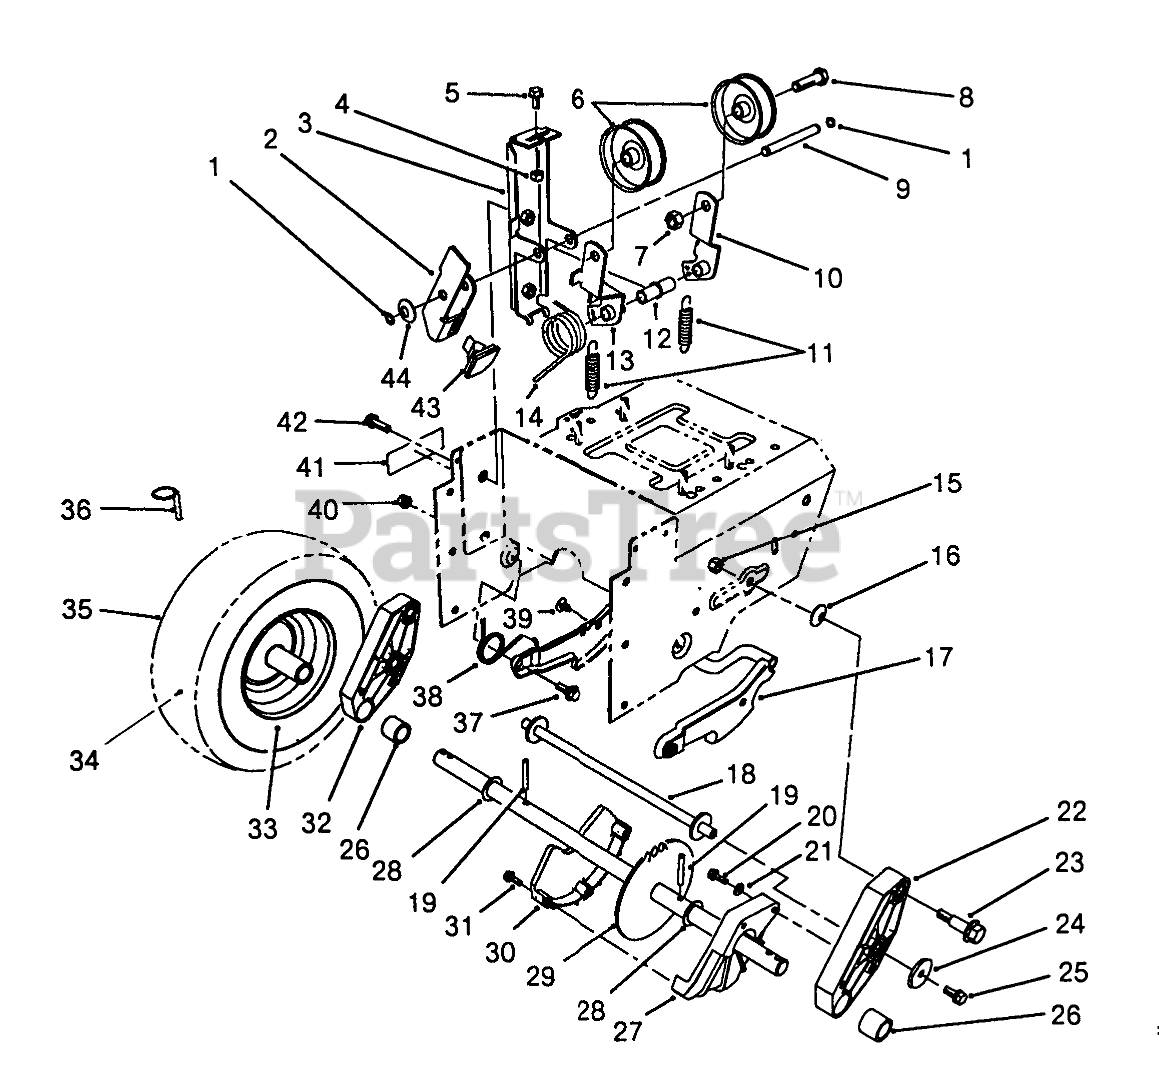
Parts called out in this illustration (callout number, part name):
1	RING-RETAINING
2	ARM-BRAKE
3	IDLER ARM BRACKET ASM
4	NUT-LOCK, NI
5	SCREW-HHF
6	PULLEY-IDLER
7	NUT-LOCK, NI
8	SCREW-HH
9	PIN-IDLER
10	ARM-IDLER, TRACTION
11	SPRING-EXTENSION
12	BUSHING-IDLER
13	ARM-IDLER, IMPELLER
14	SPRING-TORSION
15	NUT-LOCK, NI
16	WASHER-SPRING
17	Latch-Arm
18	PIVOT TUBE WA
19	PIN-ROLL, SLOTTED
20	SCREW-HWH
21	WASHER-FLAT
22	Pivot Arm Assembly L.H. (Incl. Ref. #26)
23	BOLT-SHOULDER
24	WASHER
25	SCREW-TAPTITE
26	BUSHING-AXLE
27	GUARD-CHAIN, LH
28	WASHER-THRUST
29	AXLE ASM
30	GUARD-CHAIN, RH
31	SCREW-PPH
32	Pivot Arm Assembly R.H. (Incl. Ref. #26)
33	Wheel
34	TUBE-INNER
36	PIN-LYNCH
37	SCREW-SHOULDER
38	SPRING-LATCH, TORSION
39	FASTENER-PANEL
40	NUT-LOCK, NI
41	Decal-Warning
42	SCREW-HHF
43	Brake Pad
44	WASHER-CURVED
